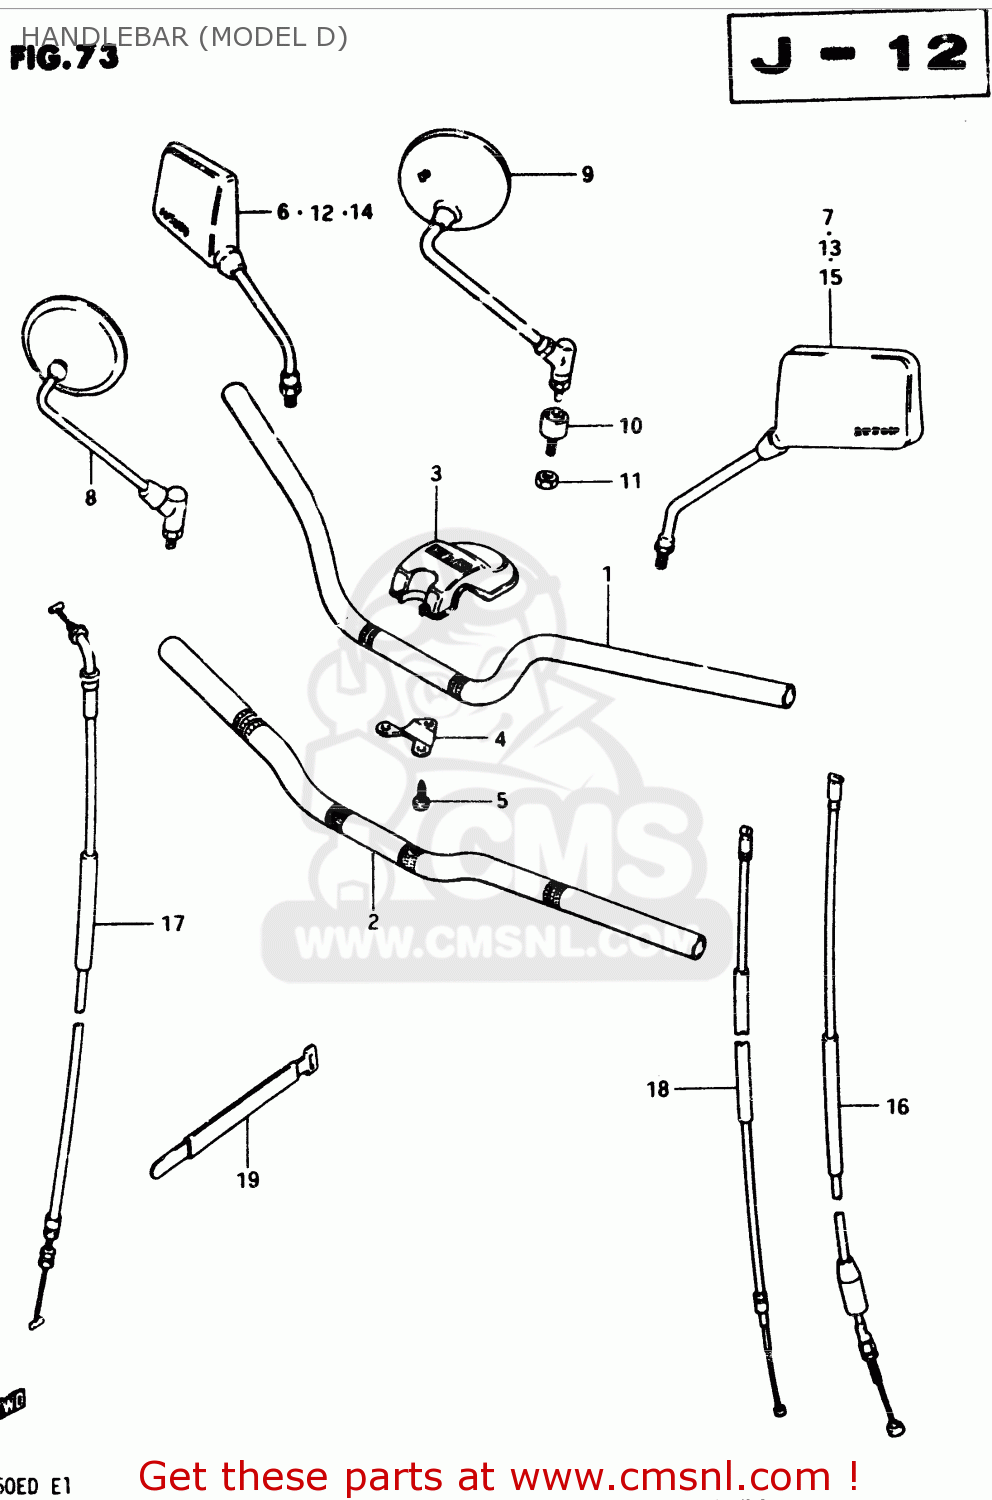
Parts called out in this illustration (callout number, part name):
1	HANDLEBAR (NEUTRAL)
2	HANDLEBAR
3	COVER,STEERING HEAD
4	BRACKET,HEAD COVER
5	SCREW
6	MIRROR ASSEMBLY,REAR VIEW
7	MIRROR ASSEMBLY,REAR VIEW
8	MIRROR ASSY,RH
9	MIRROR ASSY,RH
10	CUSHION,REAR VIEW MIRROR
11	NUT
12	MIRROR, REAR VIEW RH
13	MIRROR, REAR VIEW LH
14	MIRROR, REAR VIEW RH
15	MIRROR, REAR VIEW LH
16	CABLE ASSY,CLUTCH
17	CABLE ASSEMBLY,THROTTLE
18	CABLE, STARTER
19	CLAMP
